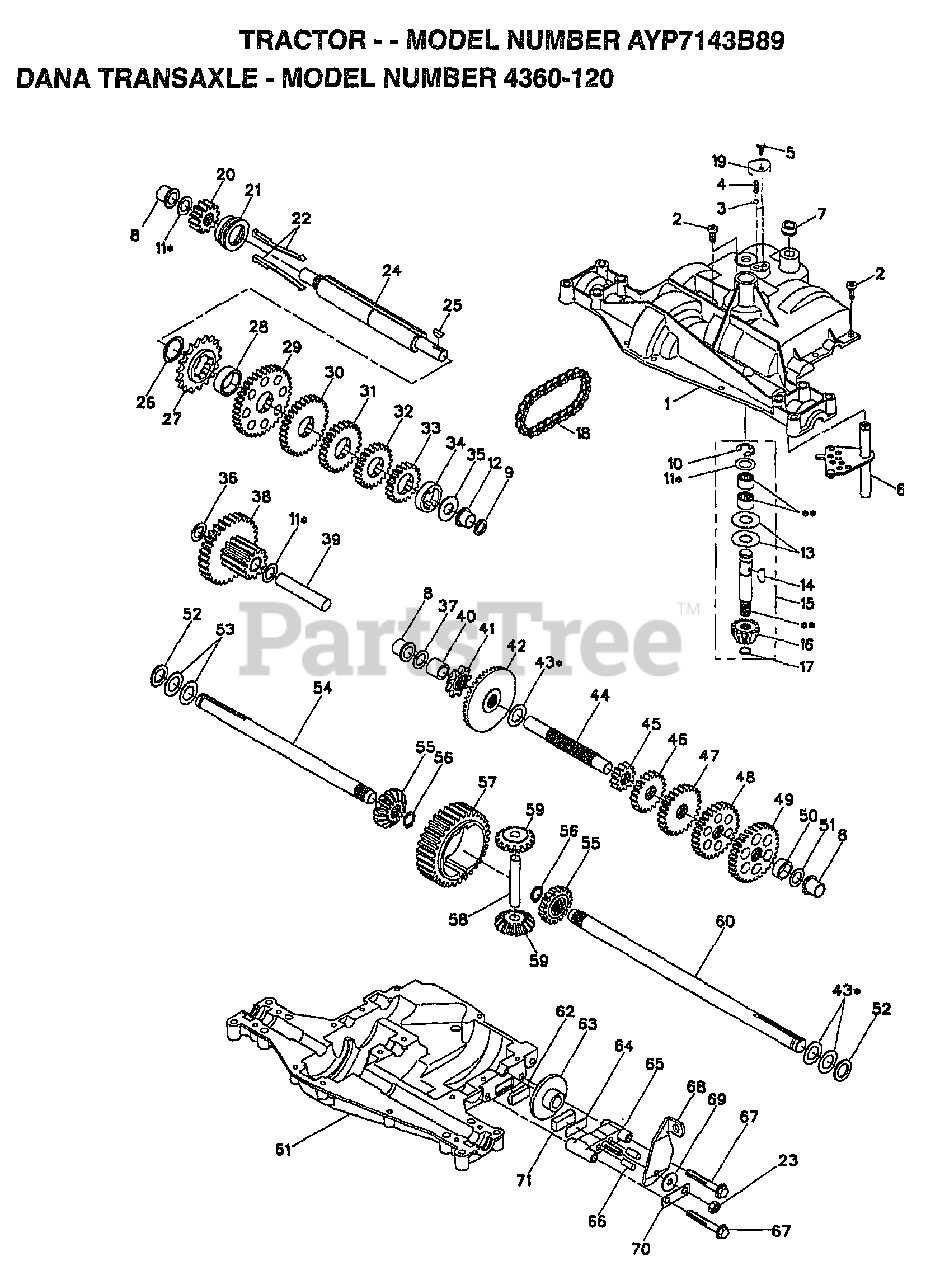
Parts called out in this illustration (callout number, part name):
1	HOUSING.UPPER.DANA.(5305J)
4	"SPRING, DETENT LT"
5	SCREW.TAPPING.1/4-20X.734
6	KIT SHIFTER ASM
9	SEAL.OIL.DAN.5508
10	RETAINING RING LT
11	ASM KIT SHIM 4689
12	BEARING.FLNG.5511
13	WASHER T
14	KEY WOODRUFF-DANA
15	INPUT SHAFT KIT 6250
16	PINION.BEVEL.12T(5620)
17	"RING,RETAINING LT"
18	"CHAIN,24 PTCH LT"
19	COVER.DETENT.(5584)
20	GEAR.SPUR.12T.(5627)
21	CLUTCH.COL.5467
22	ASM KIT CLTCH KEY
23	NUT.LOCK.5/16-24
24	SHAFT INTERM DANA
25	WOODRUFF KEY
26	"RING,RETAINING LT"
27	SPROCKET 18T T
28	SPACER YT
29	GEAR SPUR 37 TTH
30	GEAR SPUR 30T
31	GEAR 25T LT
32	GEAR SPUR 22 TT
33	SPUR GEAR 19T
34	SPACER
35	"WASHER, PLAIN LT"
36	WASHER 045
37	WASHER 031
38	ASSY.GEAR.6153 12T&30T
39	SHAFT IDLER
40	SPACER T
41	SPROCKET 9T LT
42	GEAR.BEVEL.36T(5621)
43	ASM KIT SHIM
44	SHAFT T
45	GEAR SPUR 12 TTH
46	GEAR SPUR 20T
47	"GEAR, SPUR 25T LT"
48	GEAR 28T T
49	"GEAR, SPUR 31T LT"
51	WASHER 060
52	NEOPRENE WASHER
53	WASHER 031
54	AXLE.LH(5528-1)
55	MITER 5270 12T.SPLINED
56	RING.RETAINING.(5270)
58	SHAFT T
59	MITER 5623.12T.IDLER
60	AXLE.RH.(5528-2) DANA
61	HOUSING LOWER TNS
62	PUCK T
63	BRAKE DISC. T
64	SPACER LT
66	PIN T
67	SCREW.(5562) .5/16-18X2.35
69	WASHER LT
70	BRACKET, ANTI-ROTATION
71	PUCK T
